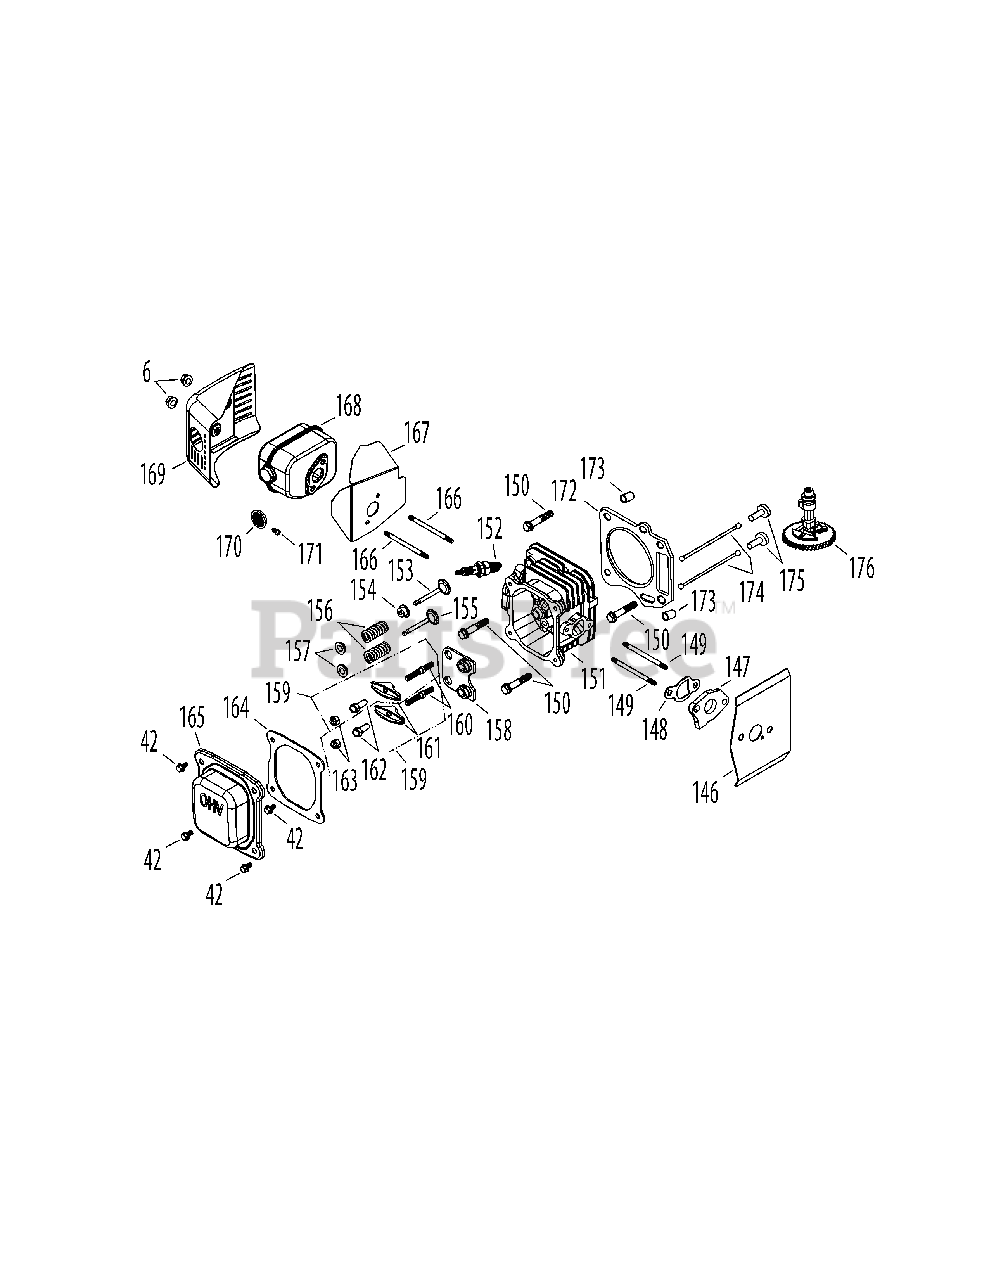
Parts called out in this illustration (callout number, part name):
6	Nut M6 X 10 Mm
42	Bolt M6×14
146	Carburetor Gasket
147	Carburetor Insulator
148	Carburetor Insulator Gasket
149	Carb Stud M6x92
150	Head Bolt M8×54
151	Cylinder Head
152	Spark Plug
153	Valve Kit
154	Valve Seal
155	Valve Kit
156	Valve Spring
157	Valve Spring Retainer
158	Push Rod Guide
159	Rocker Arm Assembly
160	Rocker Arm Stud
161	Rocker Arm
162	Valve Adjustment Nut
163	Pivot Locking Nut
164	Valve Cover Gasket
165	Valve Cover
166	Muffler Stud M6x95
166	Muffler Stud Assembly
167	Muffler Gasket
168	Muffler Assembly
169	Muffler Shield
170	Spark Arrestor
171	Spark Arrestor Screw
172	Cylinder Head Gasket
173	Cylinder Head Dowel 10×16
174	Push Rod Kit
176	Camshaft Assembly
